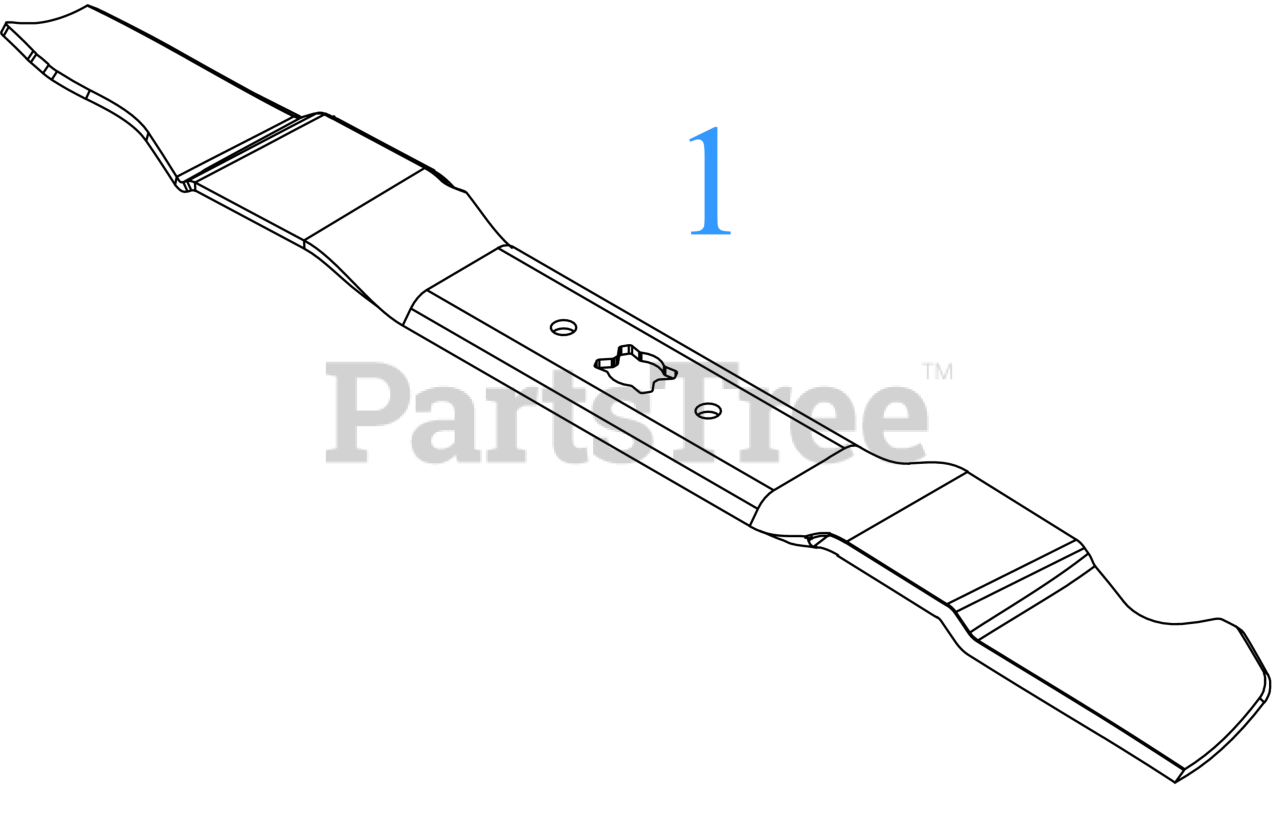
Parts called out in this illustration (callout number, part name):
1	21" BLADE (MULCH)
1	Cub Cadet 21" MULCH BLADE
1	Troy-Bilt 21" MULCHING BLADE (0741A)
1	Genuine Factory Parts 21" MULCHING BLADE (0741A)
1	21" BLADE (MULCH) (XTREME)
